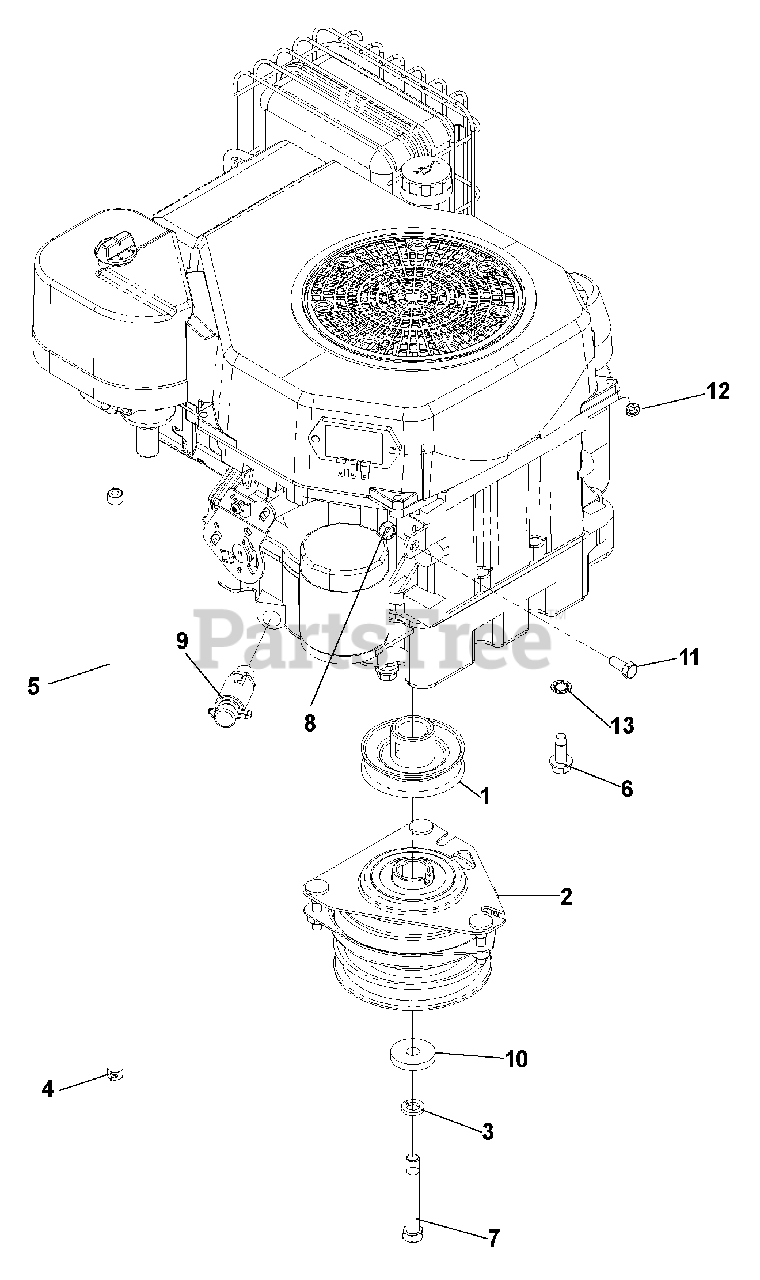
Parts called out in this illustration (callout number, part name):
1	PULLEY, ENGINE, KOHLER, COMMAND
2	CLUTCH
3	LOCKWASHER, 7/16
4	CLAMP, HOSE
5	FUEL LINE, 24"
6	BOLT, 3/8-16 X 1, THREAD FORMING
7	HCS, 7/16-20 X 3
8	NUT, 5/16, NYLOC
9	PLUG, EZ OIL DRAIN
10	CLUTCH WASHER
11	HCS, 5/16-18 X 3/4
12	NUT, 1/4C, THIN NYLOC
13	WASHER, 3/8, INTERNAL TOOTH
